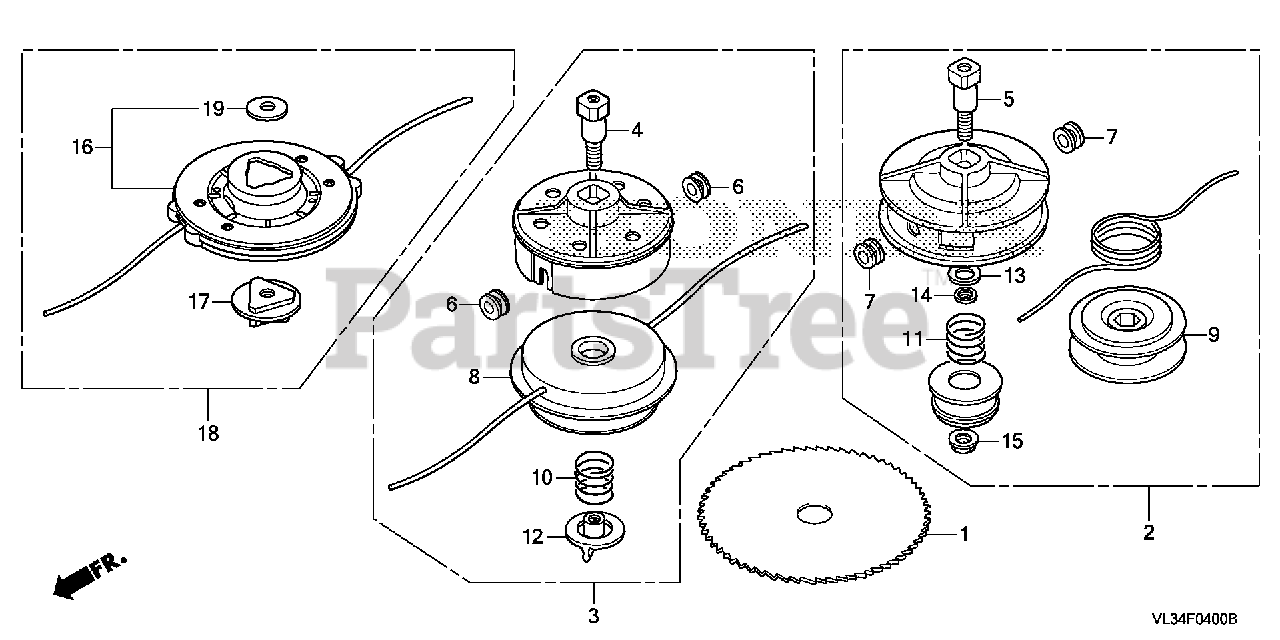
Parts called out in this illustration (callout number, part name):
1	BLADE, BRUSH (50TXX10")
3	CUTTER ASSY., NYLON
4	SHAFT (10X1.25) (LH)
8	SPOOL
16	CUTTER ASSY., NYLON
17	COLLAR, NYLON CUTTER
19	WASHER, PLAIN (10.5MM)
